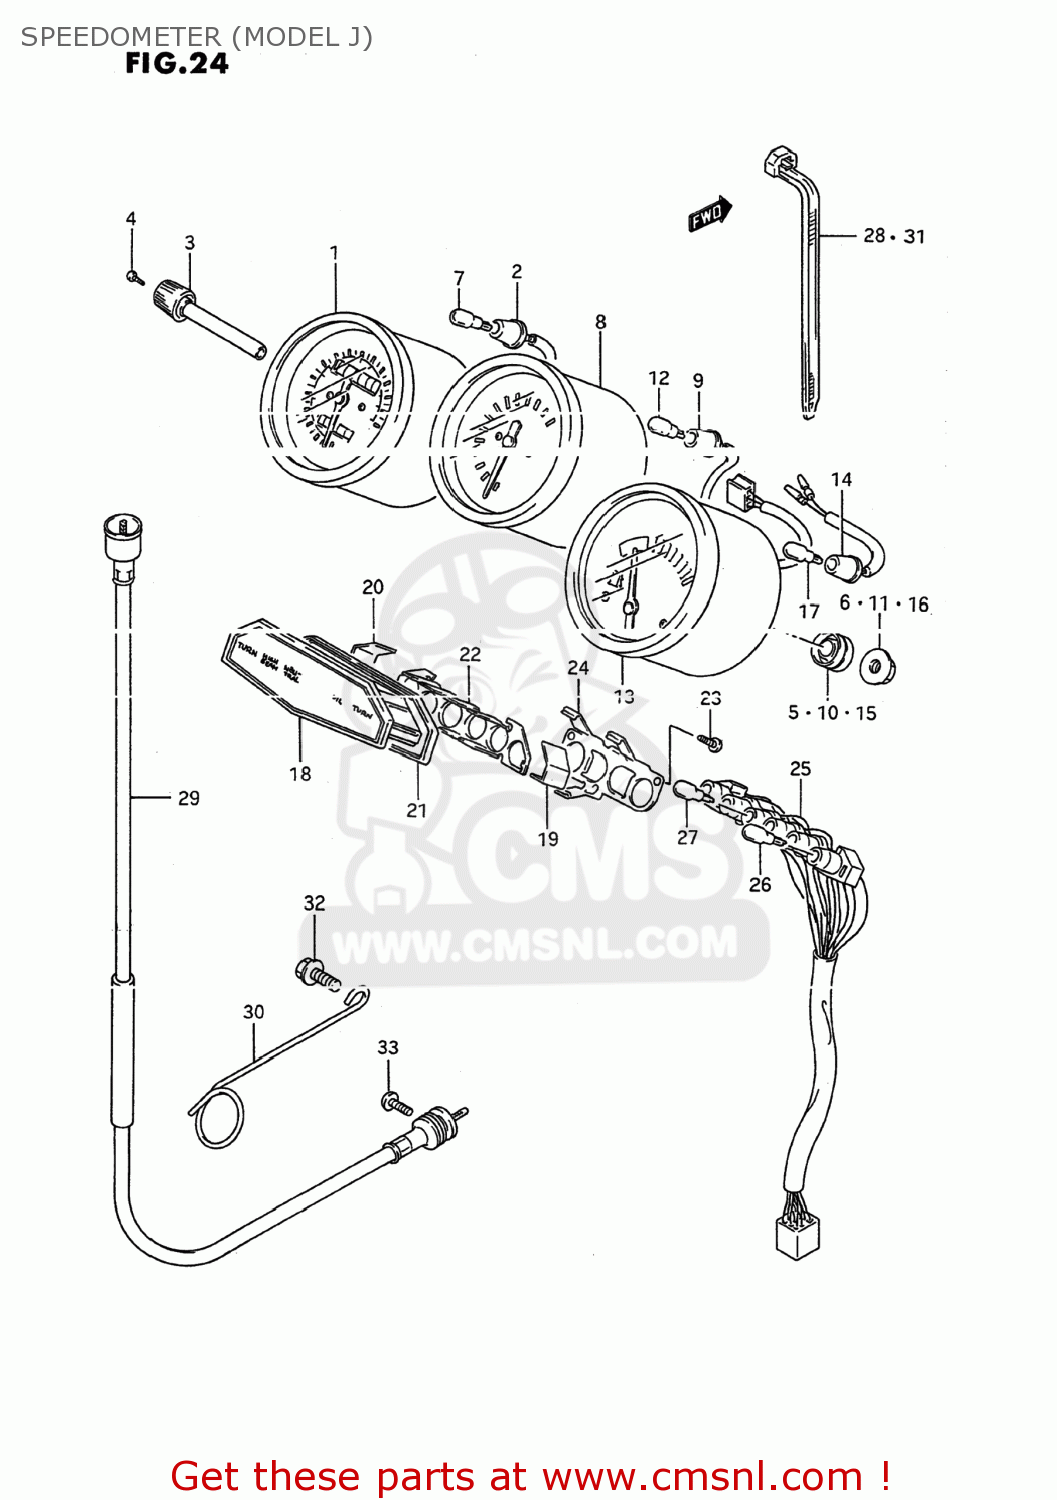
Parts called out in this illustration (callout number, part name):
1	METER ASSY,SPE
2	SOCKET
3	KNOB,TRIP
4	SCREW,TRIP KNOB
5	CUSHION
6	NUT
7	BULB(12V3W,WB371,T7)
8	TACHOMETER ASSEMBLY
9	SOCKET
10	CUSHION
11	NUT
12	BULB(12V3W,WB371,T7)
13	METER ASSEMBLY,FUEL
14	SOCKET
15	CUSHION
16	NUT
17	BULB(12V3W,WB371,T7)
18	BOX ASSY
19	PLATE,TURN,R
20	PLATE,TURN,L
21	CUSHION
22	PLATE,PILOT LAMP
23	SCREW
24	LOCK PLATE
25	SOCKET
26	BULB(12V1.7W,WB372,T7)
27	BULB(12V3W,WB371,T7)
28	CLAMP(L:125)
29	CABLE ASSY,SPEEDOMETER
30	CLAMP,SPEEDOMETER CABLE
31	CLAMP(L:125)
32	BOLT
33	SCREW
